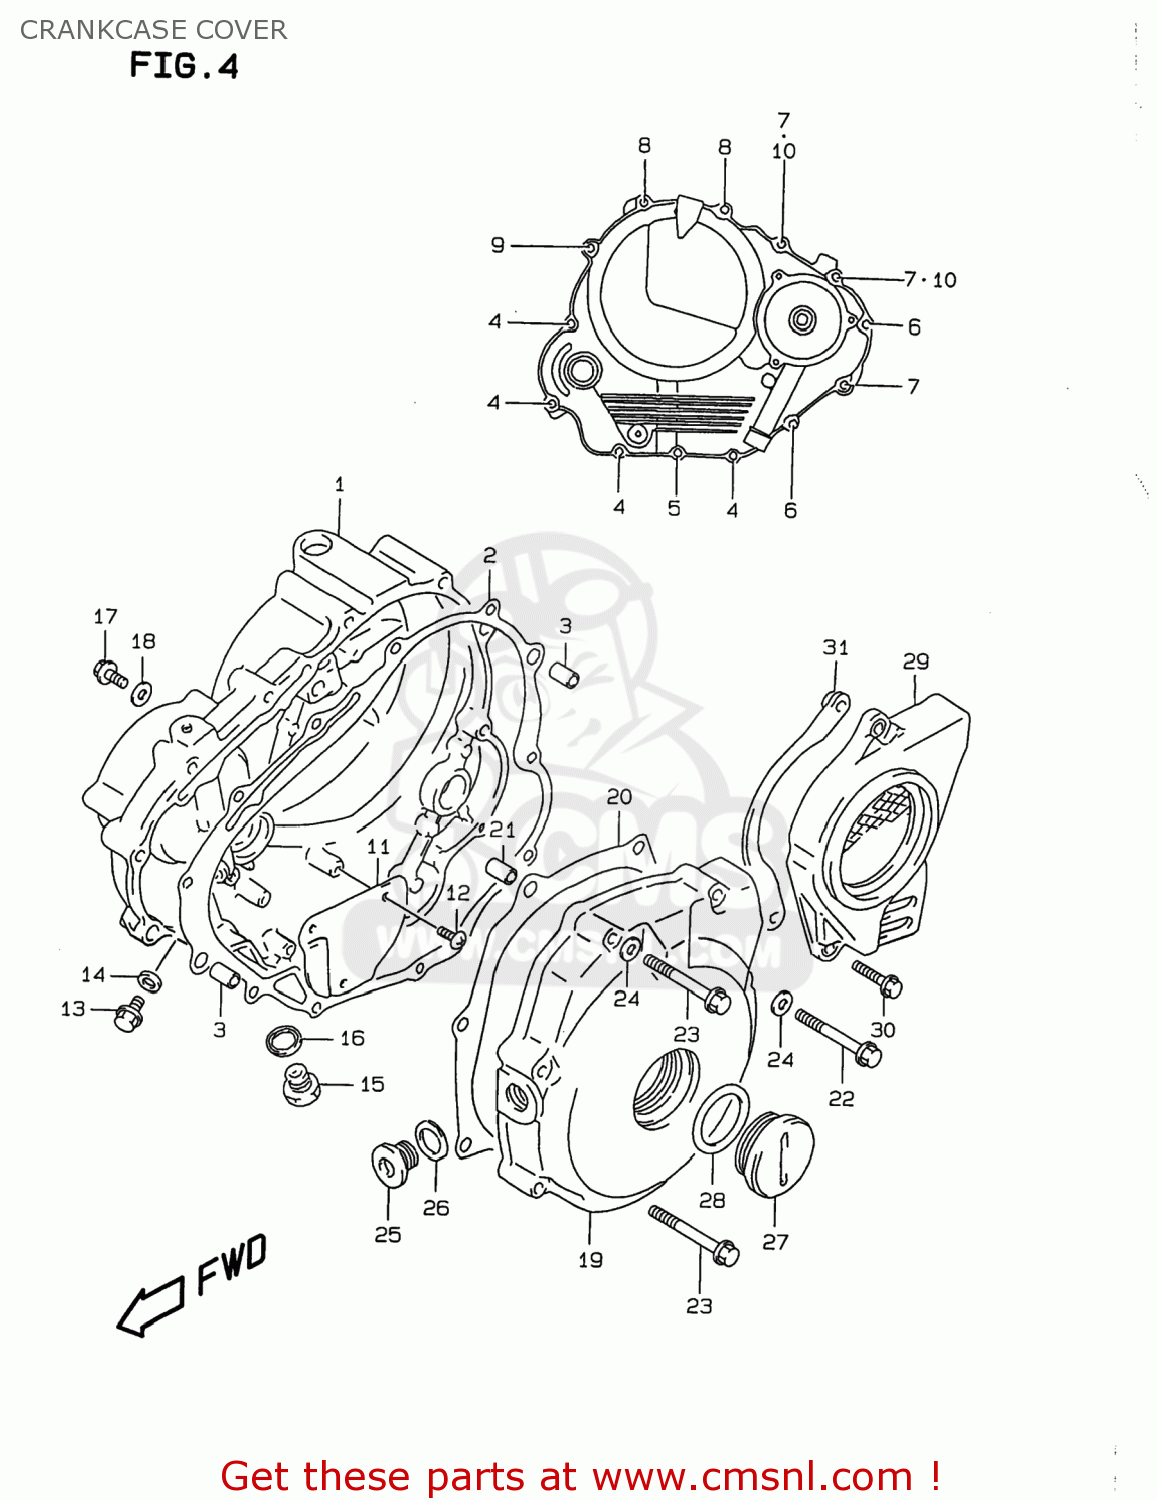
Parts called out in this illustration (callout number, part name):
1	COVER,CLUTCH
2	GASKET,CLUTCH COVER (NAS)
3	PIN
4	SCREW
5	BOLT,G/S SWITC
6	BOLT
7	BOLT
8	BOLT
9	BOLT
10	GASKET(5.8X11X1.2) (NAS)
11	SEPARATOR,OIL RETURN
12	SCREW
13	BOLT(6X8)
14	GASKET(6.2X11X1).2 (NAS)
15	PLUG(10X6.8)
16	GASKET(10X14X3.6) (NAS)
17	SCREW(6X10)
18	GASKET(5.8X11X1.2) (NAS)
19	COVER,MAGNETO
20	GASKET,MAGNETO COVER (NAS)
21	PIN
22	BOLT
23	BOLT
24	GASKET(5.8X11X1.2) (NAS)
25	PLUG,14X12
26	GASKET(13.8X18.8X4.8) (NAS)
27	PLUG(SILVER)
28	O RING(D:3.1,ID:32.7)
29	COVER,ENGINE SPROCKET
30	SCREW
31	PLATE,FR CHAIN GUIDE
